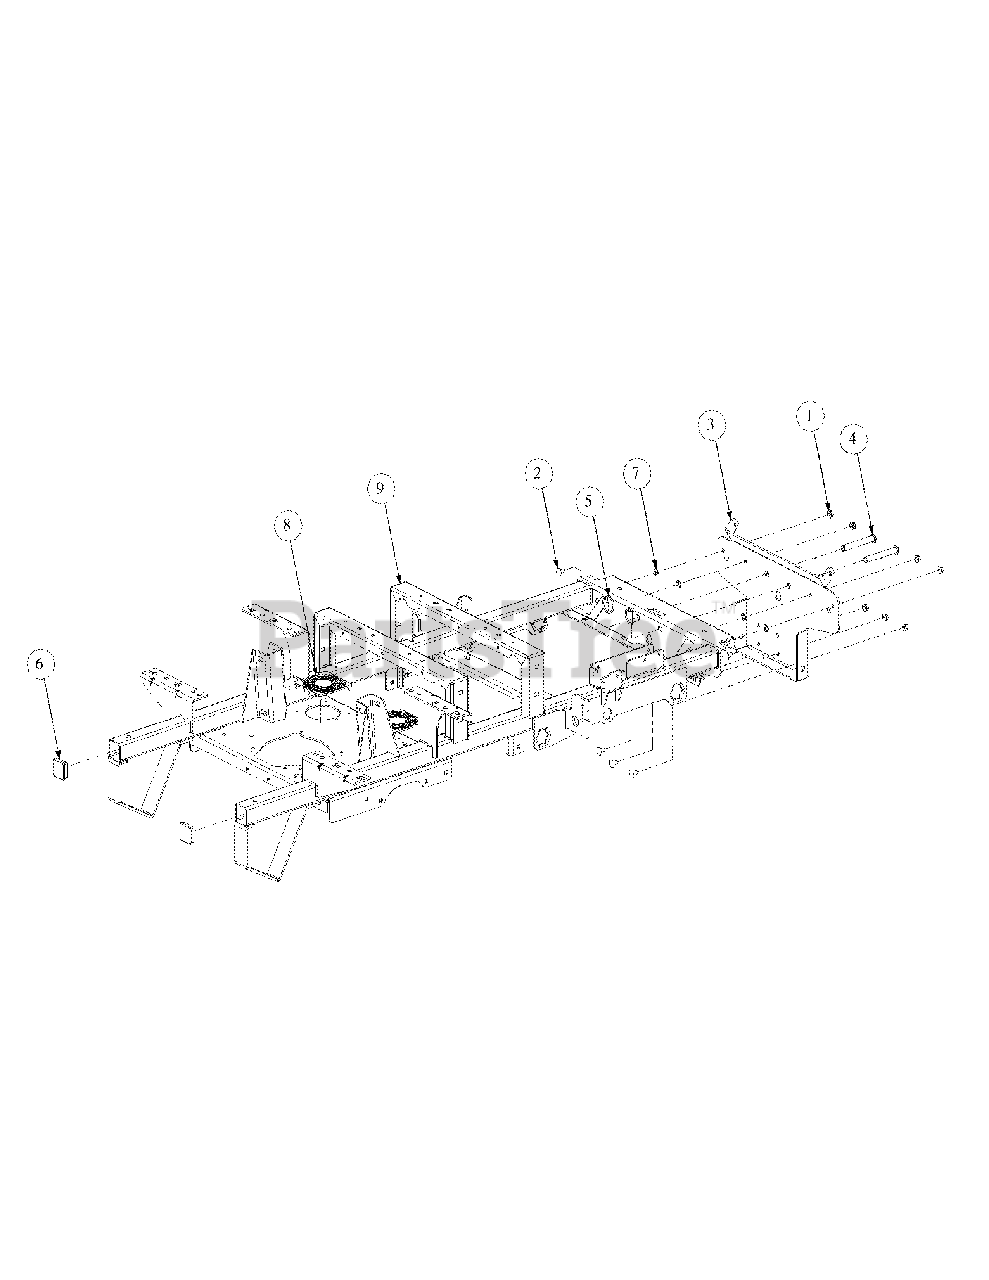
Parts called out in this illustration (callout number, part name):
1	Hex Nut, 3/8-16 Flange Lock
2	Carriage Bolt, 3/8-16 x .75 Long
3	Bracket Assembly, Frame, Front
4	Clevis Pin, .625 Dia x 4.375 Long
5	Linch Pin, 3/16 Dia.
6	Plug, Square Tube
7	Push Retainer, 3/8
8	Cover, Hydro Fan
9	Frame Assembly
